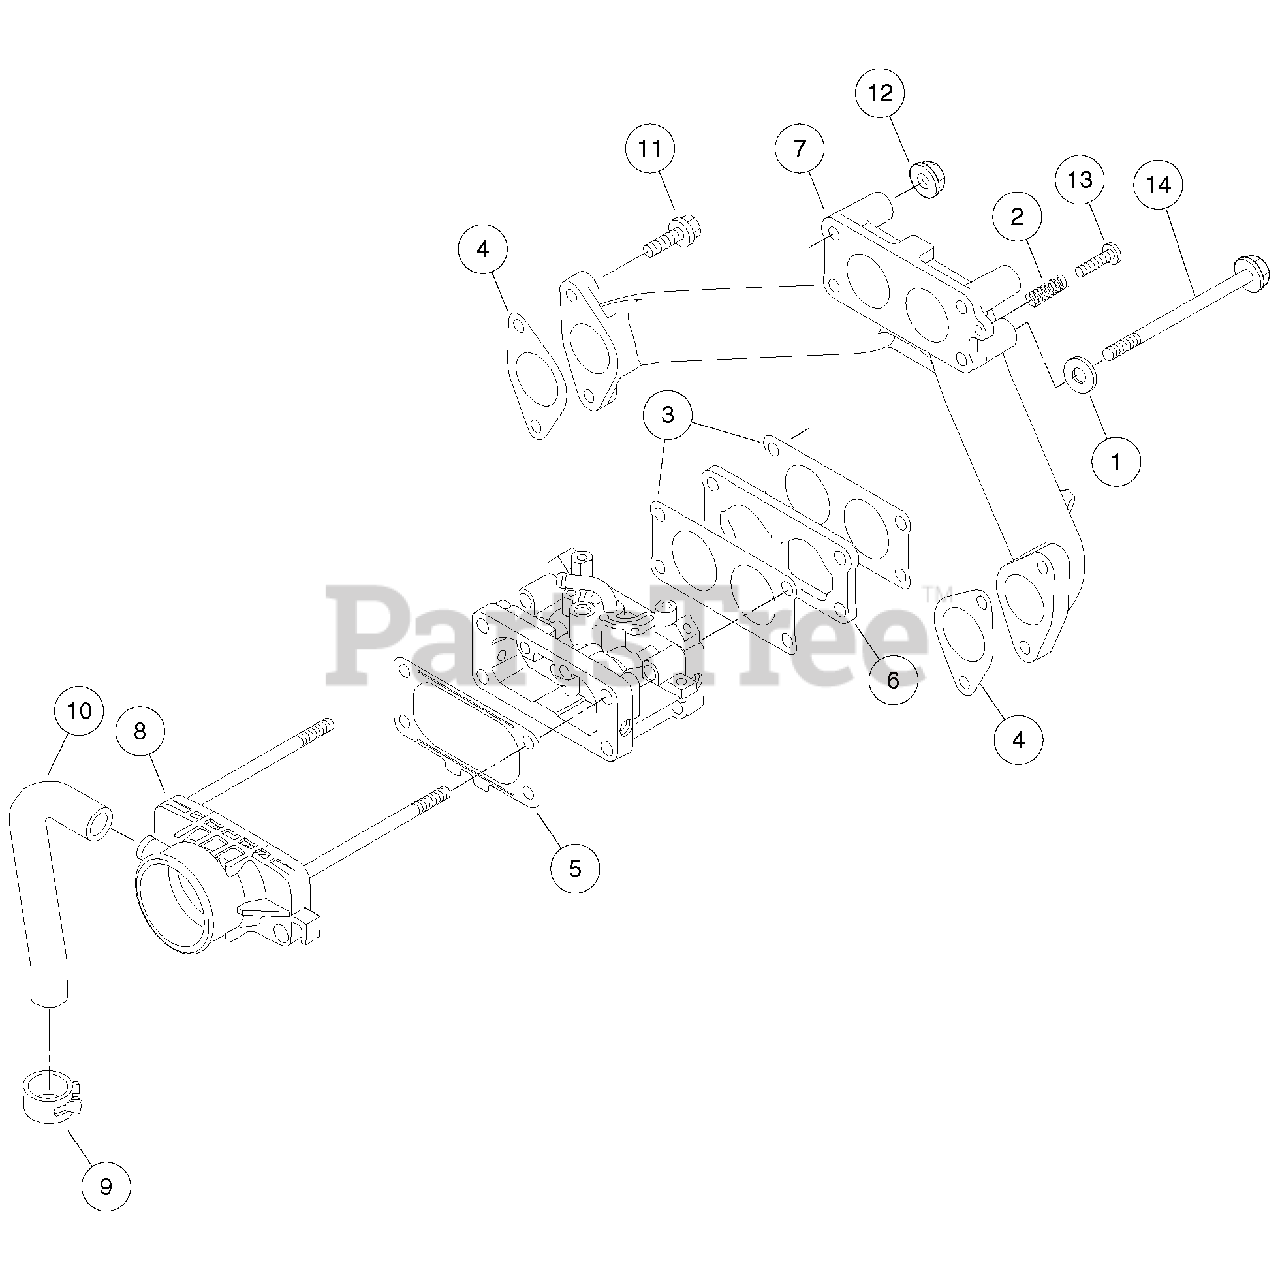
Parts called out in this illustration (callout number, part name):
1	Washer, M6 Flat
2	Spring, Fh
3	Gasket, Carburetor, Fh
4	Gasket, Manifold, Fh
5	Gasket, Air Filter, Fh
6	Insulator, Manifold, Fh
7	Manifold, Intake, Fh
8	Pipe, Intake Adapter, Fh
9	Clamp, Crankcase Vent, Fh
10	Tube, Crankcase Vent, Fh
11	Bolt, Flanged, M6 X 20, Kaw
12	Nut, Carburetor, M6
13	Screw, Carburetor, M4 X 20
14	Bolt, Flg, Carburetor, M6x105
